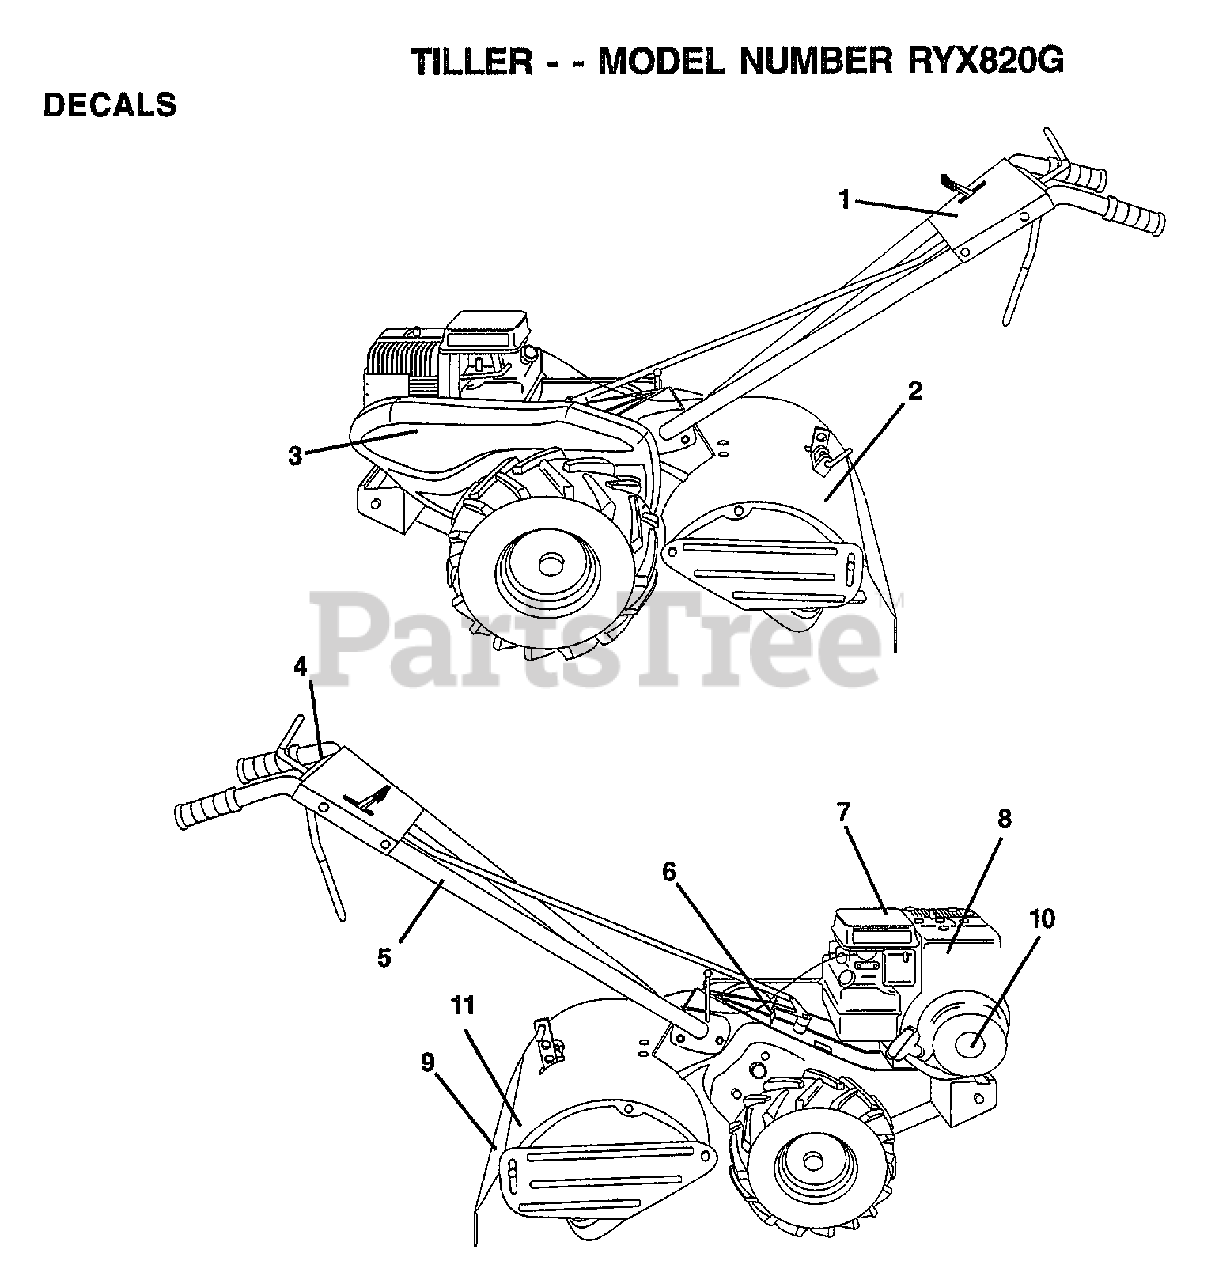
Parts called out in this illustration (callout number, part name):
3	DECAL, LOGO
5	DECAL-PLACEMENT
6	DECAL CRT
7	DECAL TI
8	DECAL
9	DECAL-WARNING
11	DECAL.EURO.ST.CE.
